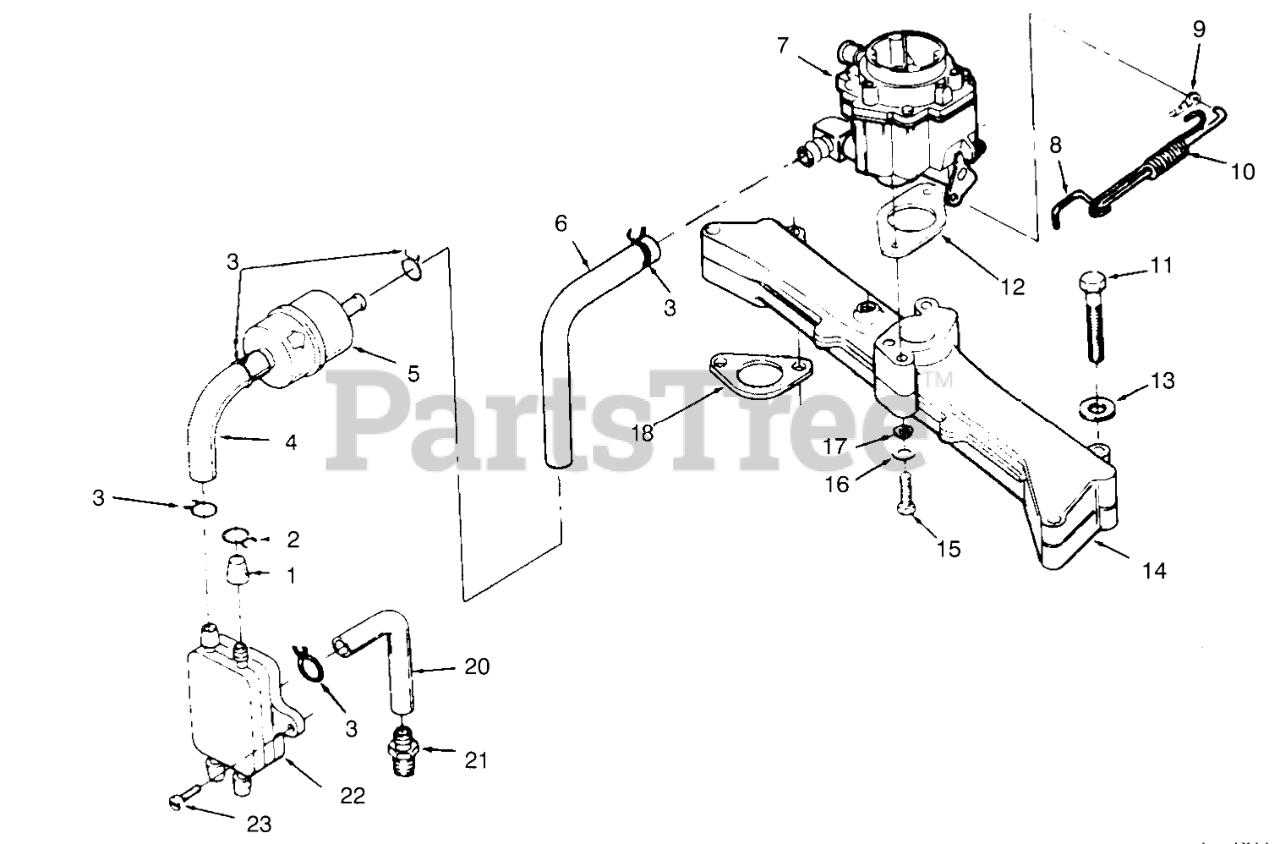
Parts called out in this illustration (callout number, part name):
1	CAP-FUEL OUTLET
2	CLAMP
3	CLAMP-HOSE
5	FILTER-FUEL
6	HOSE - FUEL
7	Carburetor
8	ROD-GOV CONTROL
10	Spring-Governor Rod
11	SCREW-HH
12	GASKET-CARBURETOR
13	WASHER-FLAT
14	MANIFOLD - INTAKE
15	HEX HD CAP SCR
16	WASHER-FLAT
17	WASHER-FLAT
18	GASKET-MANIFOLD TO BLOCK
20	HOSE-VACUUM
21	FITTING-BARB
22	Pump-Fuel (Incl.Ref.#1 & 2)
23	Screw
